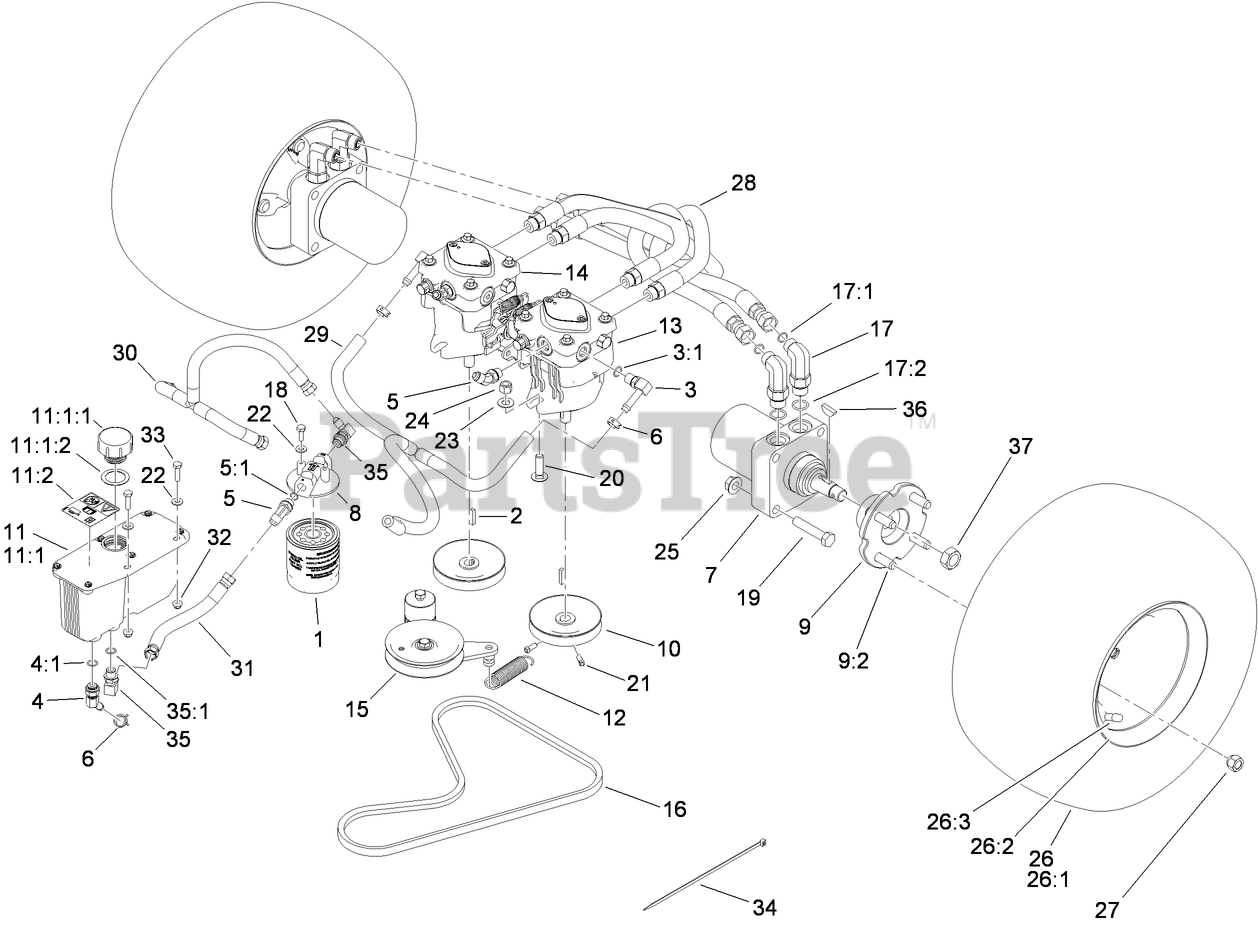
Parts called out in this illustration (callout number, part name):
1	ELEMENT-FILTER, 25 MICRON
3	FITTING-ELBOW, 90
3:1	O-RING
4	FITTING-BARBED, 45 DEG
4:1	O-RING
5	FITTING-ELBOW, 45 DEG
5:1	O-RING
6	Clamp-Hose
7	HYD MOTOR ASM
8	HEAD-FILTER
9	WHEEL HUB ASM
9:2	STUD-TYPE, DRIVE
10	PULLEY-PUMP
11	HYD RESERVOIR ASM
11:1	Reservoir-HYD
11:1:1	CAP-RESERVOIR, HYD
11:1:2	GASKET-CAP
11:2	DECAL-WARNING
12	SPRING-EXTENSION
13	HYDRAULIC PUMP ASM
14	HYDRAULIC PUMP ASM
15	PUMP IDLER ASM
16	BELT-V
17	FITTING-ELBOW 90
17:1	O-RING
17:2	O-RING
18	SCREW-HH
19	SCREW-HH
20	BOLT-CARR
21	SCREW-SET
22	WASHER-FLAT
23	WASHER-FLAT
24	NUT-LOCK, NI
25	NUT-HF
26	WHEEL AND TIRE ASM
26:1	TIRE (18 X 9.50-8, 4 PLY)
26:2	RIM-8 INCH
26:3	STEM-VALVE
27	NUT-LUG
28	HYD HOSE ASM
29	HYD HOSE ASM
30	HYD HOSE ASM
31	HYD HOSE ASM
32	NUT-HF
33	SCREW-HH
34	TIE-CABLE
35	FITTING-ELBOW, 90 DEG
35:1	O-Ring
36	KEY-WOODRUFF
37	NUT-MOTOR, WHEEL
